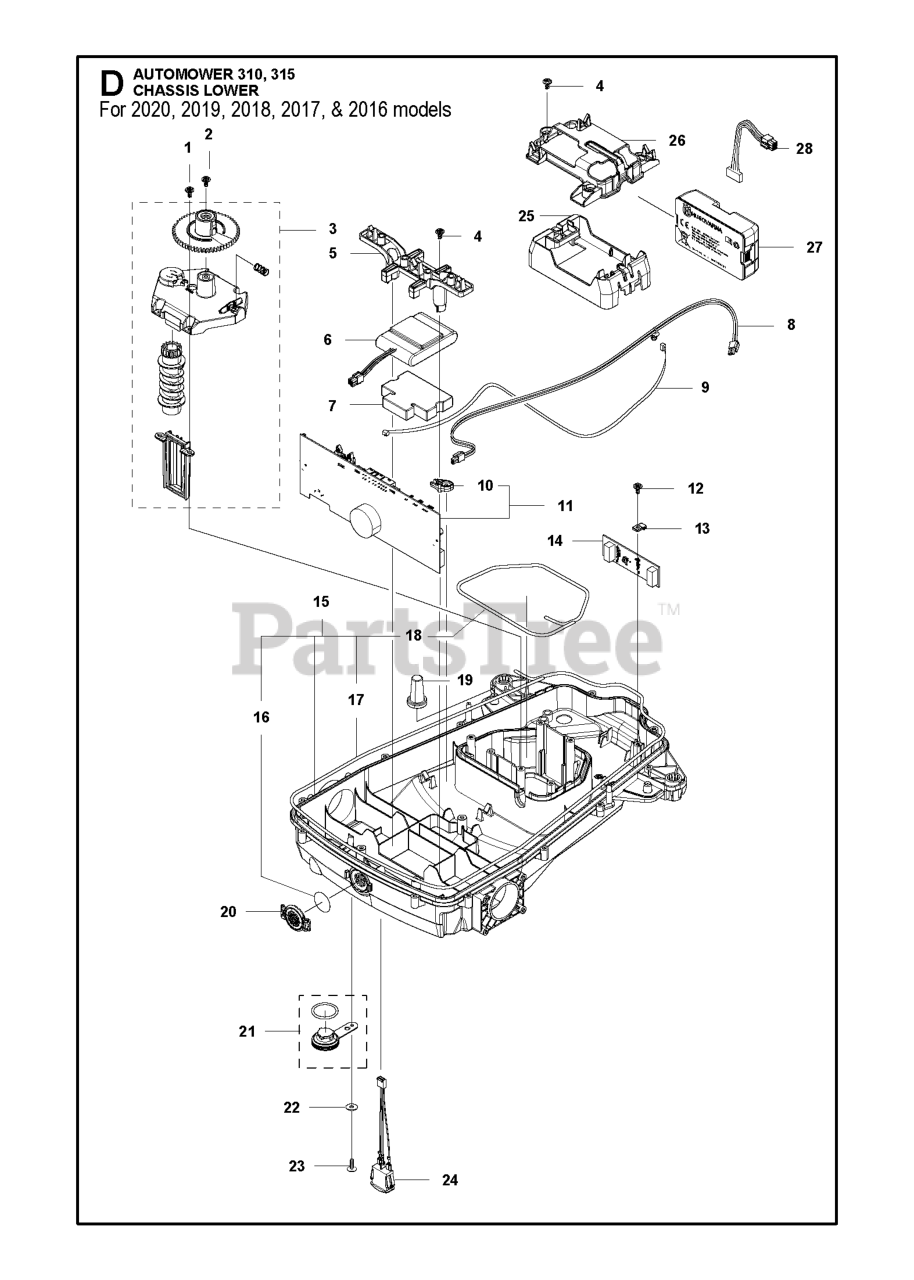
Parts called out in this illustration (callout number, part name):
1	SCREW ITXPANT
2	SCREW ITXPANT
3	COVER KIT
4	SCREW ITXPANT
5	HOLDER BATTERY
6	BATTERY LI-ION
7	WEIGHT 470G
8	LOOM CHARGING LINK
9	LOOM LOOP SENSOR
10	CLIP PCB
11	PRINTED CIRCUIT ASSY MAIN BOAR
12	SCREW ITXPANT
13	CLAMP PCB
14	PRINTED CIRCUIT ASSY LOOP SENS
15	CHASSIS KIT LOWER
16	KIT AIR FILTER KIT 305 - 10 PC
17	SEALING STRIP P 15 CHASSI LOW
18	SEALING STRIP P15 UPPER
19	COLUMN FRONT
20	COVER AIR FILTER
21	PLUG KIT
22	WASHER
23	SCREW ITXPANT
24	LOOM ON/ OFF
27	BATTERY:18V, 2.0AH, 36.0WH TYP
28	WIRING ASSY BATTERY CABLE
